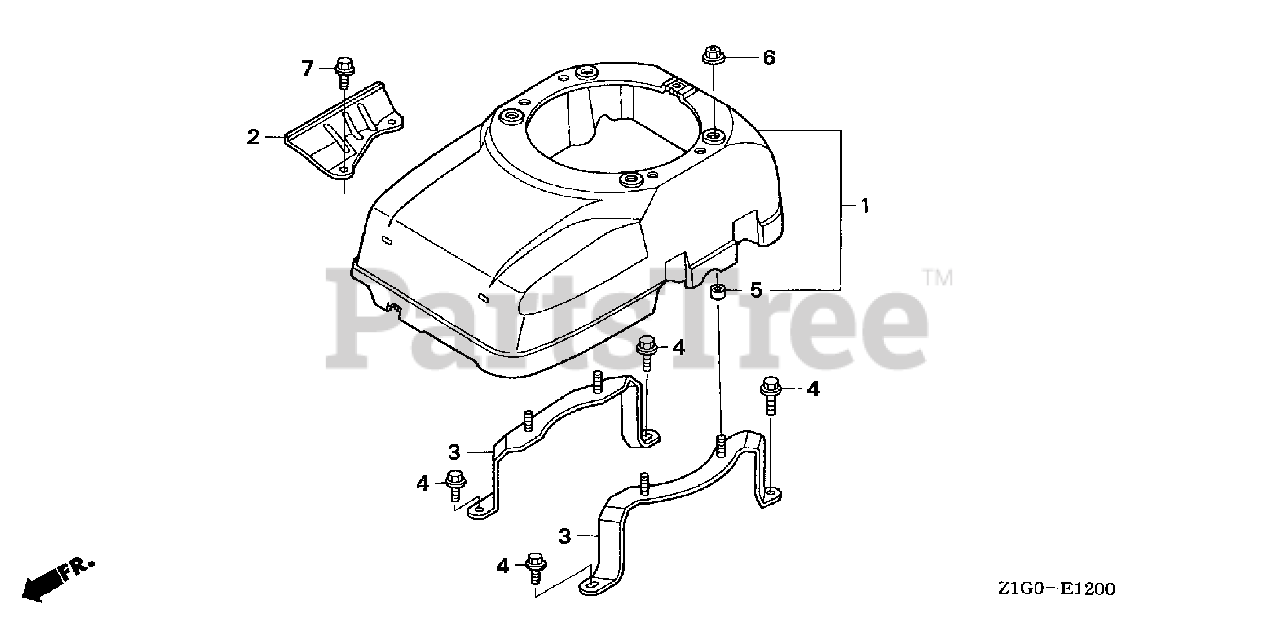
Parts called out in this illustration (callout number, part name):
1	COVER, FAN *R280* (POWER RED)
3	BRACKET, FAN COVER
4	BOLT, FLANGE (6X16) (CT200)
5	COLLAR, FAN COVER
